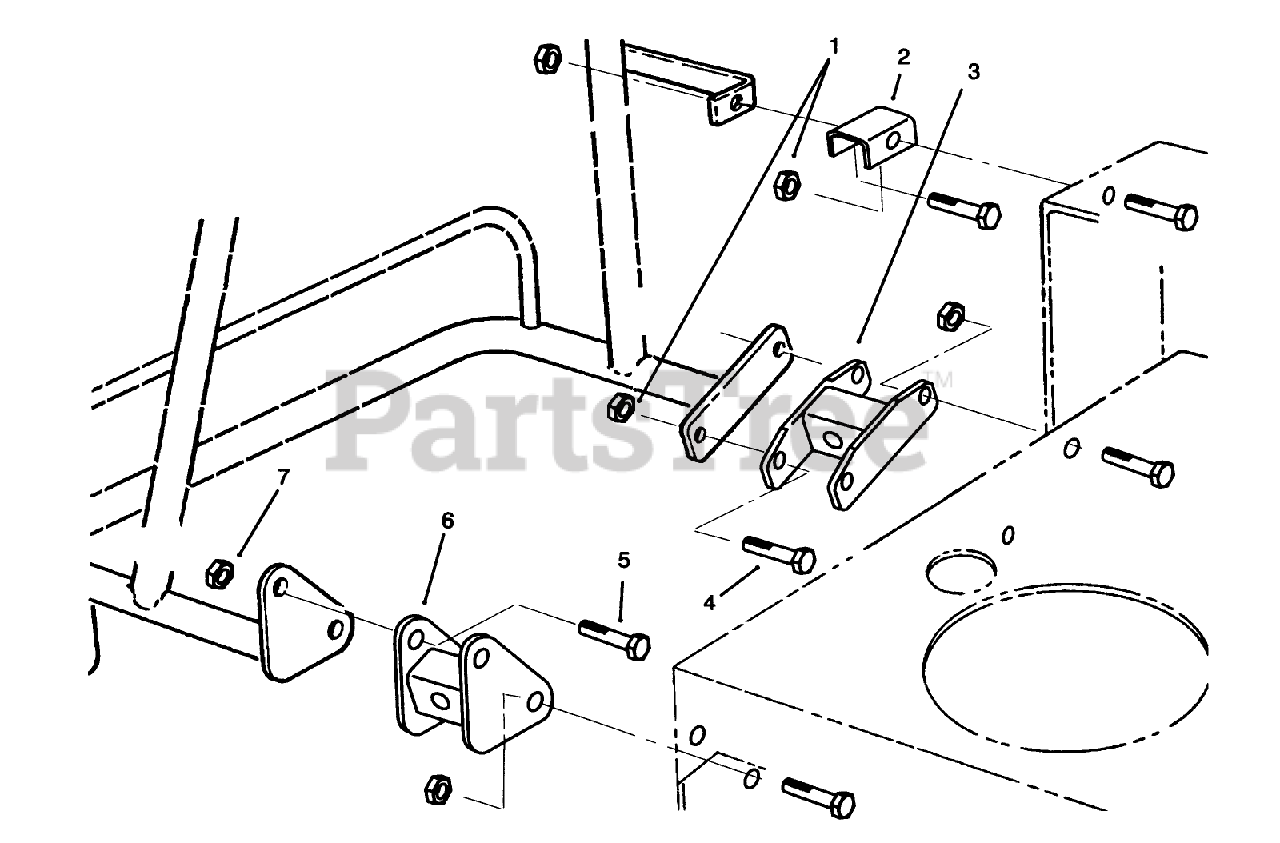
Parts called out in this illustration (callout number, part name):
1	NUT-LOCK, NI
2	Bracket
3	Adapter
4	SCREW-HH
5	SCREW-HH
6	Adapter
7	NUT-LOCK, NI
